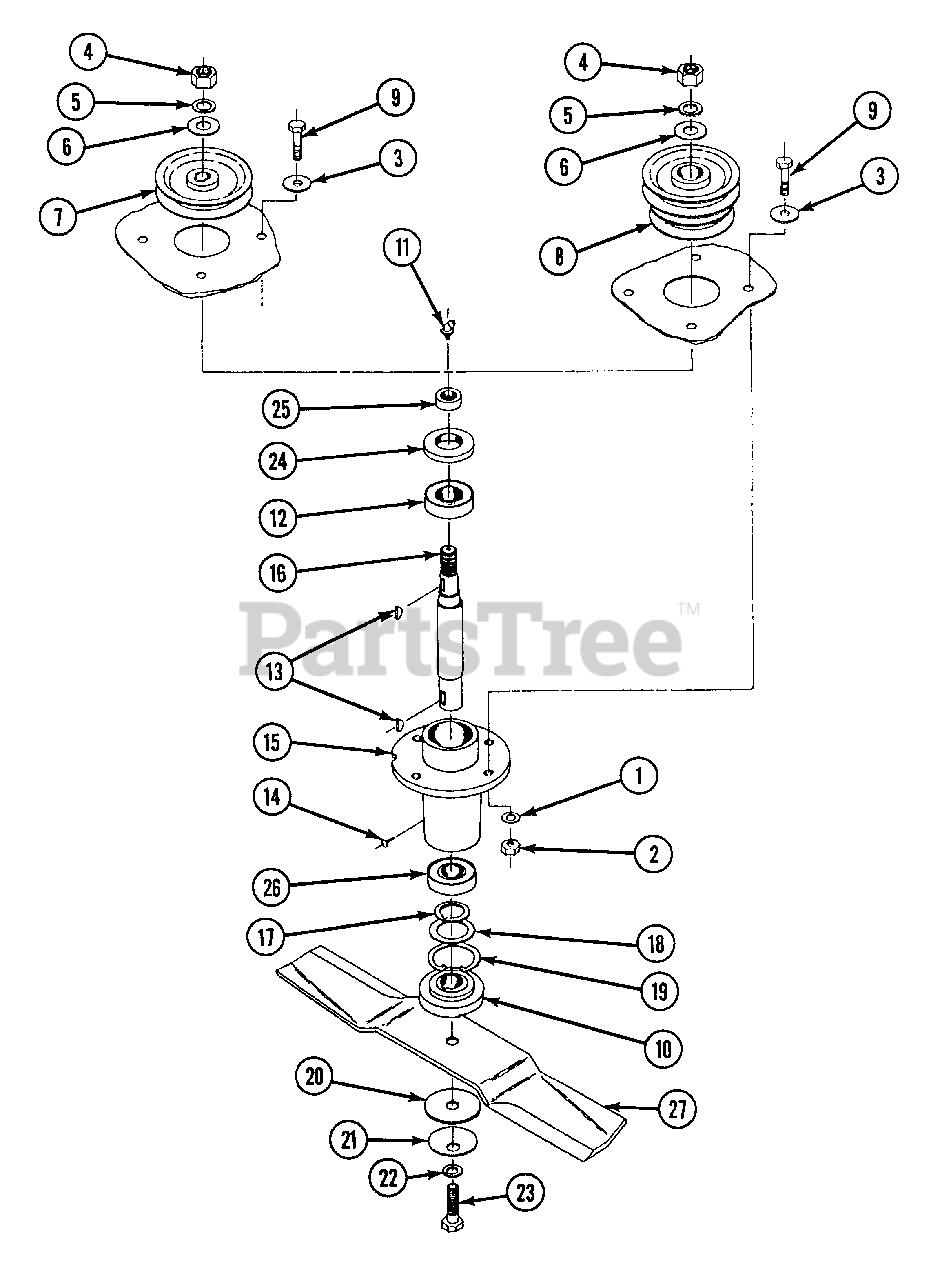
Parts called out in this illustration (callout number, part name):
1	LOCKWASHER, SPLT SPRNG: 3/8
2	LOCKNUT, M-F: 3/8-24NF
3	FLAT WASHER, STD: 3/8
4	NUT, HEX JAM: 3/4
5	LOCKWASHER, SPLT SPRNG: 3/4
6	FLAT WASHER, NARROW: 3/4
7	PULLEY, SINGLE GROOVE: 15/16 BORE 4" OD
8	PULLEY, 2 GROOVE: 15/16 BORE
9	CAPSCREW, HX HD: 3/8-24NF X 1-1/2
10	BLADE SPACER
11	GREASE FITTING, 45 DEGREE
12	BEARING, 25 MM ID (NO SEALS)
13	KEY, WOODRUFF: 1/4 X 3/4
14	DRIVE SCREW: NO.4 X 3/16
15	DECK SPINDLE HOUSING
16	DECK SPINDLE SHAFT
17	ARBOR SPACER
18	SEAL WASHER
19	RETAINING RING
21	WASHER, CUPPED
22	LOCKWASHER, SPLT SPRNG: 1/2
23	CAPSCREW, HX HD: 1/2-13 X 1-1/2 GR 5
24	OIL SEAL
25	SEAL RACE
26	BEARING, 25 MM ID (BOTTOM SEAL ONLY)
27	BLADE, LOW LIFT, 17" CUT (48" DECK)
